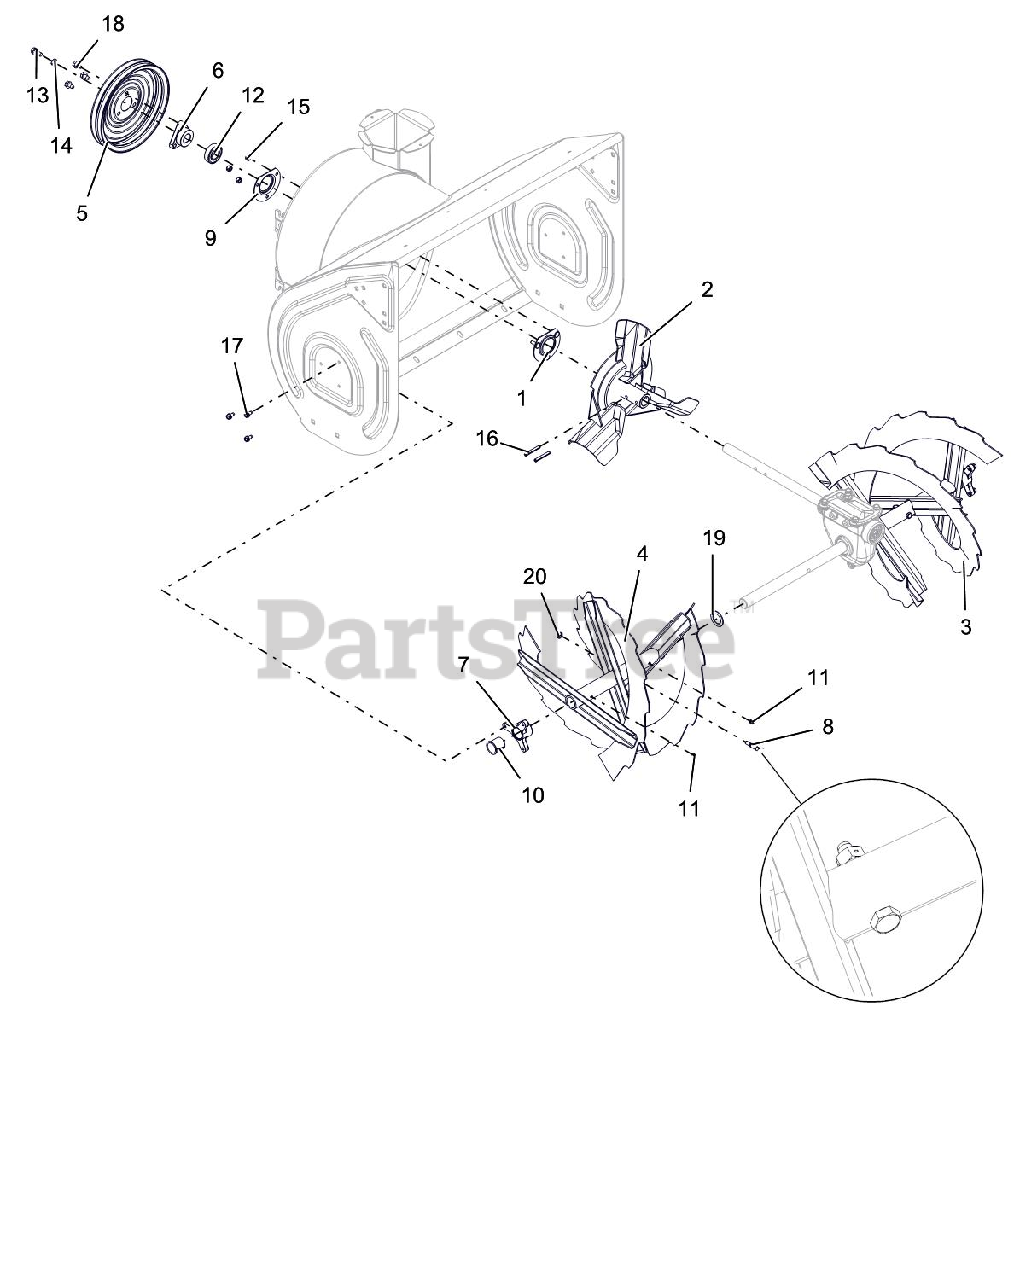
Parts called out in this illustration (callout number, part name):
1	BEARING FLANGE
2	IMPELLER, 3 BLADE-14"
3	RAKE, LH-28"(1 ID X 15.75 OD)
4	RAKE, RH-28"(1 ID X 15.75 OD)
5	PULLEY, SPIN FORM DUAL GROOVE
6	PULLEY HUB, D-BORE .87 PRO
7	BUSHING, RAKE SHAFT 1"
8	SHEAR BOLT SERVICE ASSEMBLY
9	BEARING FLANGE
10	BSHG-FLG SPLIT NYLINER 1.0" HP
11	ZERK,FITTING .25X.125 DRIVE IN
12	BRG-BALL .876X1.75X.50 RSTFP
13	BLT-HEX .31-24X.75 YWZC GR5
14	WSHR-LK .312X.097 HVY YWZC
15	@NUT-LK-CTR .25-20 YWZC
16	PIN-ROLL .250X1.75
17	SCR-TAP .25-20X.50 HWH TR YWZ
18	@SCR-TAP .31-18X.50 HWH TR YWZ
19	WSHR-FL-STL 1.010X1.505X.062YZ
20	@NUT-LK-CTR .31-18 YWZC
